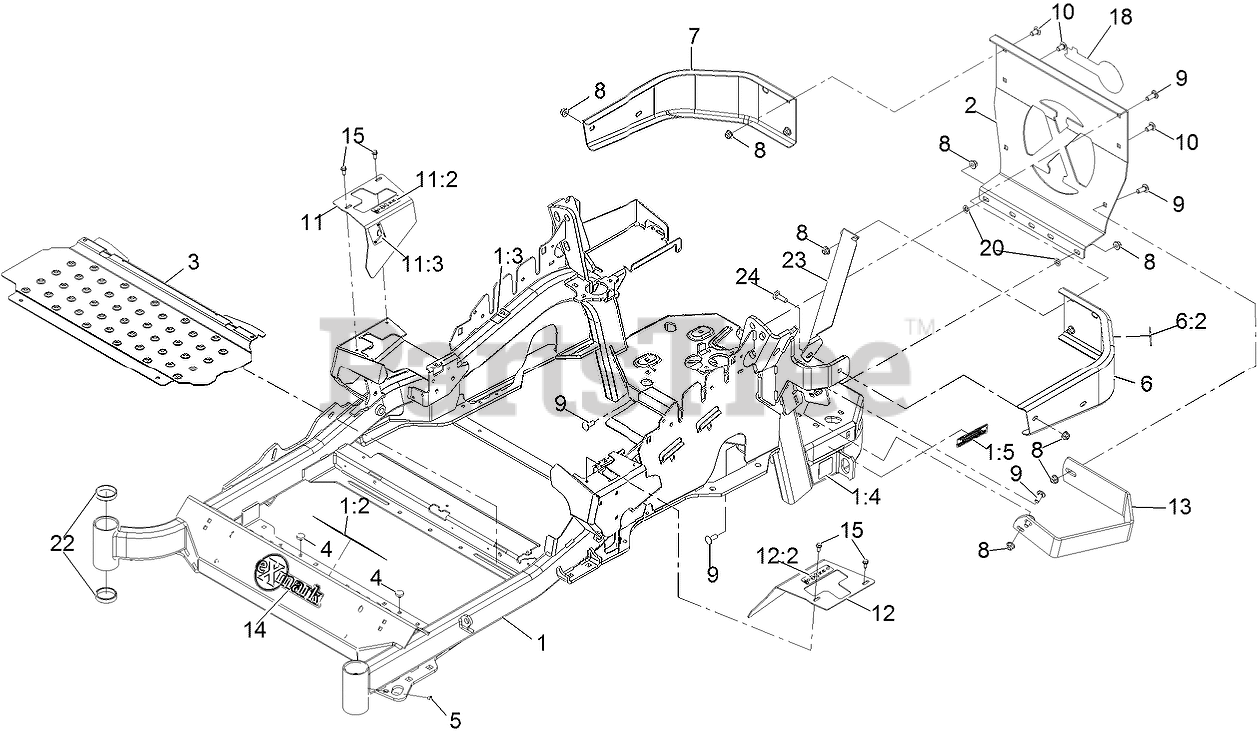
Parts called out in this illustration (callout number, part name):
1	MAINFRAME ASM
1:2	DECAL-DANGER
1:3	DECAL-WARNING
1:4	DECAL-HAZARD, PINCHED FINGER
1:5	DECAL-ARRESTOR, SPARK
2	PLATE,REAR GUARD
6	LH BUMPER ASM
6:2	DECAL-WARNING
7	BUMPER-RH
8	NUT-HF, NI
9	SCREW-CARR
10	SCREW-CARR
11	RH MOTION CONTROL COVER ASM
11:2	DECAL-CONTROL, MOTION
11:3	DECAL-PARK BRAKE, CE
12	LH MOTION CONTROL COVER ASM
12:2	DECAL-CONTROL, MOTION
13	GUARD-MUFFLER
14	DECAL-EXMARK
15	SCREW-HWH
18	DECAL, EXMARK LOGO
20	NUT-PUSH
22	CUP-BEARING
24	BOLT-CARR
